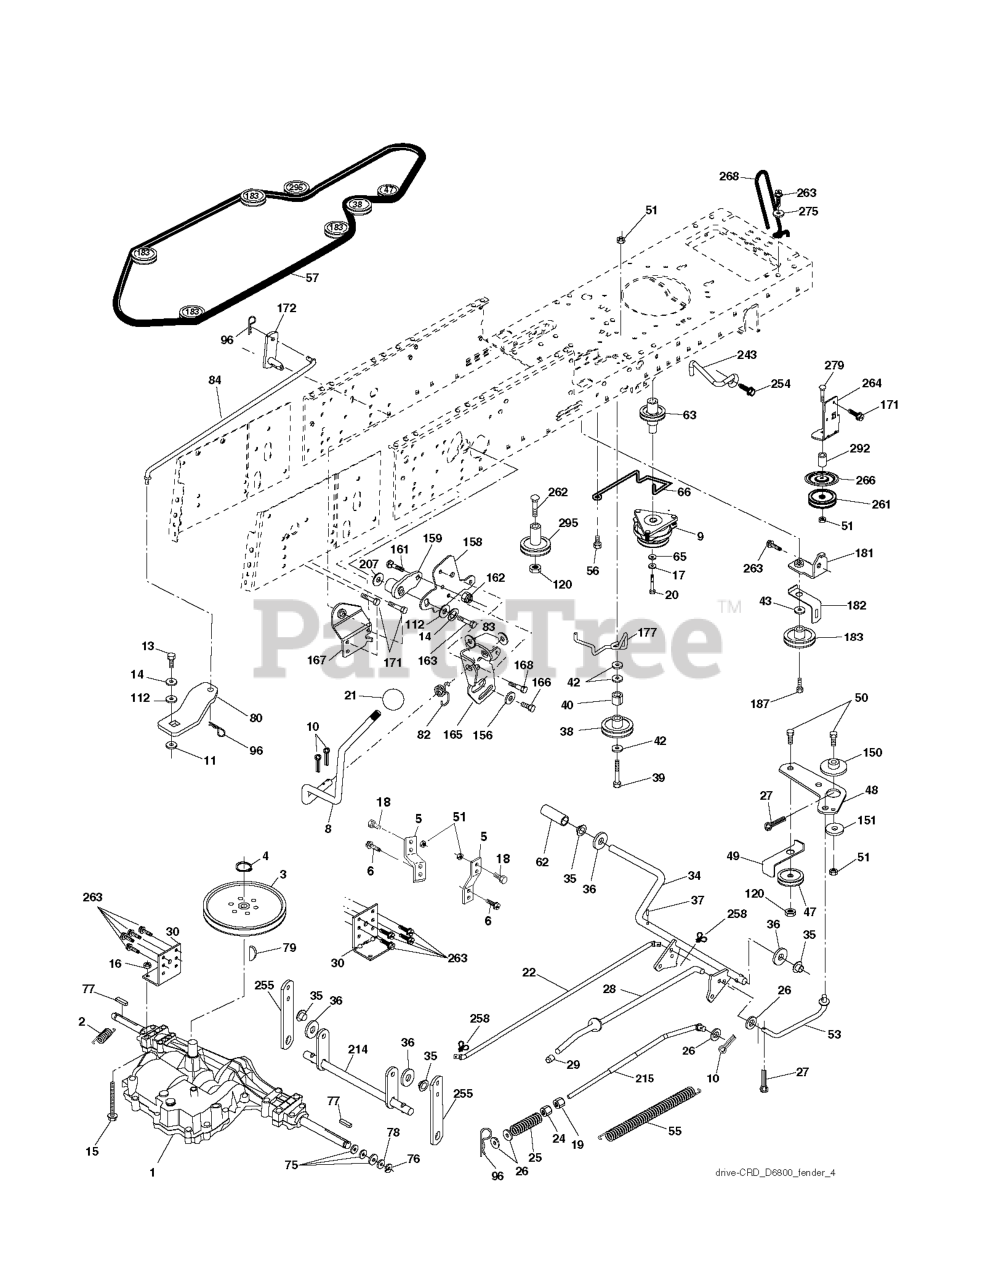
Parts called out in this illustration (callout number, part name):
2	SPRING,BRAKE RETURN
3	PULLEY
4	RETAINING RING LT
5	STRAP TORQUE
6	SCREW 5/16"
8	ROD SHIFT FENDER ADJUST LT
9	CLUTCH.ELECTRIC.OGURA.EURO.
10	PIN COTTER
11	WASH-SHFT PLT LT
13	BOLT 1/4-28X3/4
14	LOCKWASHER
15	BOLT HEX 5/16-18 GR 5
16	NUT.71038.31-18.HEX.NYLOCK
19	NUT
20	BOLT HEX 7/16-20X4-1/4"
21	KNOB.DUCKHEAD.1/2
22	ROD
24	NUT
25	SPRING ROD LT
26	WASHER
27	COTTER PIN
28	ROD, PARKING BRAKE
29	CAP
30	BRKT, MOUNT TRNSAXLE
34	SHAFT, FOOT PEDAL
35	BEARING.NYLON
37	DRIVE PIN
38	PULLEY.FLAT
42	WASHER
47	IDLER PULLEY
48	BELLCRANK, CLUTCH
49	RETAIN BELT
50	BOLT.3/8-16X1.50
53	LINK.CLUTCH.7.66.2005
55	SPRING, RETURN LT
56	SCREW.3/8-16
62	PEDAL COVER T
63	PULLEY.ENGINE.CVX.LT
65	LOCKWASHER
66	KEEPER BELT ENGINE
77	SQUARE KEY
79	KEY STD (1373) DANA
82	SHIFT SPRING
83	WASHER
84	LINK.T/A.CRD.D6800.18"CLR
96	RETAINER M
120	NUT LOCK FLG 3/8-16 UNC
150	BUSHING.BELLCRANK.GRD.DR
151	WASHER 12/32X2X10GA
156	WASHER.SRRTD.5/16
158	BRACKET
159	RB HUB.SHIFT
161	BOLT
162	NUT.CROWNLOCK.1/4
165	RP BRACKET
166	CAPSCREW.HXHD.FLG.5/16-18X.625
167	BRACKET.SUPT.SHIFT.CRD
168	BOLT.SHOULDER.5/16-18X
181	BRACKET
182	BELT GUIDE
183	PULLEY.V-IDLER.GRND.DR
187	BOLT.5/16-18X1.25
207	WASHER NYL
214	LEVER
243	BRACKET, ANTI-ROTATION
254	SCREW 3/8-16X1
255	SHAFT
258	CLIP RETAINER
261	FLAT IDLER PULLEY
263	SCREW, 3/8-16X3/4
266	PROTECTOR
268	GUARD MUFFLER
275	WASHER
292	SPACER
295	PULLEY IDLER COMPOSITE
